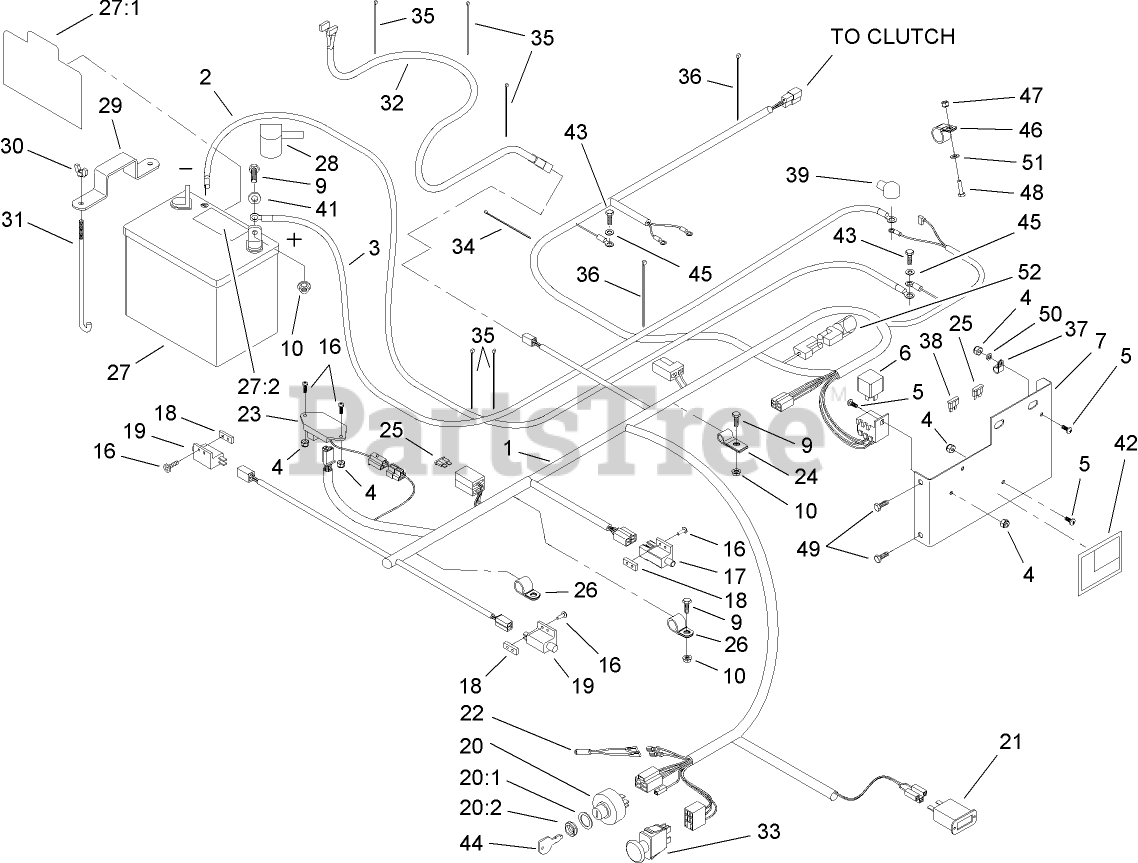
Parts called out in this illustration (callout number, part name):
1	Harness-Wire
2	WIRE-GROUND
3	WIRE-BATTERY, POSITIVE
4	NUT-LOCK, NI
5	SCREW-PPH
7	PANEL-EFI
9	SCREW-HH
10	NUT-HF
16	SCREW-PPH
17	SWITCH
18	PLATE-TAPPED
19	SWITCH-OPEN, NORMALLY
20	Key Switch ASM
20:1	WASHER-TOOTH, INTERNAL
20:2	NUT-HH
21	METER-HOUR
22	INDICATOR-LED, RED
23	MODULE-DELAY, SEAT
24	CLIP-LOOM
25	FUSE-BLADE TYPE, 20 AMP
27	BATTERY
27:1	Decal-Battery
27:2	Decal-Battery
28	INSULATOR-BATTERY
29	STRAP-HOLDDOWN
30	WINGNUT
31	BOLT-HOLDDOWN
32	HARNESS-WIRING, SEAT
33	SWITCH-DELTA
34	TIE-CABLE
35	TIE-PLASTIC
36	TIE-PLASTIC
37	CLIP-LOOM
38	FUSE-BLADE TYPE, 10 AMP
39	INSULATOR-SOLENOID
41	WASHER-FLAT
42	DECAL-RELAY / FUSE
43	SCREW-HH
44	KEY-IGNITION
45	WASHER-PLAIN
46	CLIP-LOOM
47	NUT-LOCK, NI
48	SCREW-HH
49	SCREW-HH
50	WASHER-FLAT
51	WASHER-FLAT
